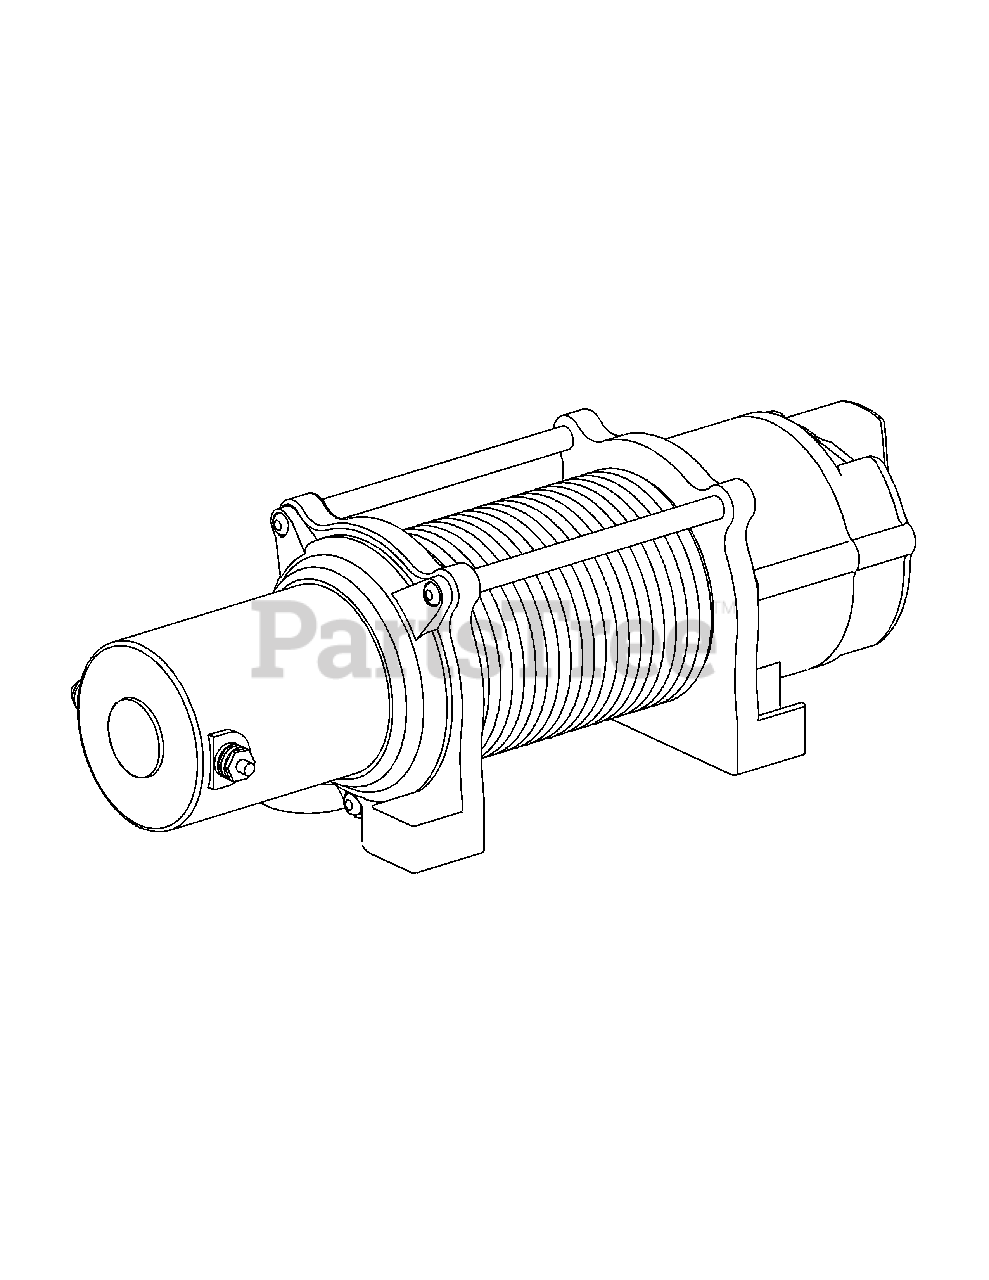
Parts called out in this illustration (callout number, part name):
1	Wire Rope Assembly, 7/32 x 55’
2	Roller Fairlead Kit
3	Hook Kit with Strap
4	Hook Strap
5	Contractor Kit
6	Socket Assembly Remote Control
7	Remote Control 10 Foot Lead
8	Switch Kit Mini Rocker
9	Cable Assembly Kit, 6 Ga. Bl/Yw 36"
10	Cable Assembly Kit, 6 Ga. Bk/Rd 36"
11	Electrical Boot, 6 Ga. (2 Pair)
12	Winch Mounting Bracket
13	Winch Bumper Plate
14	Fuse Mounting Bracket
